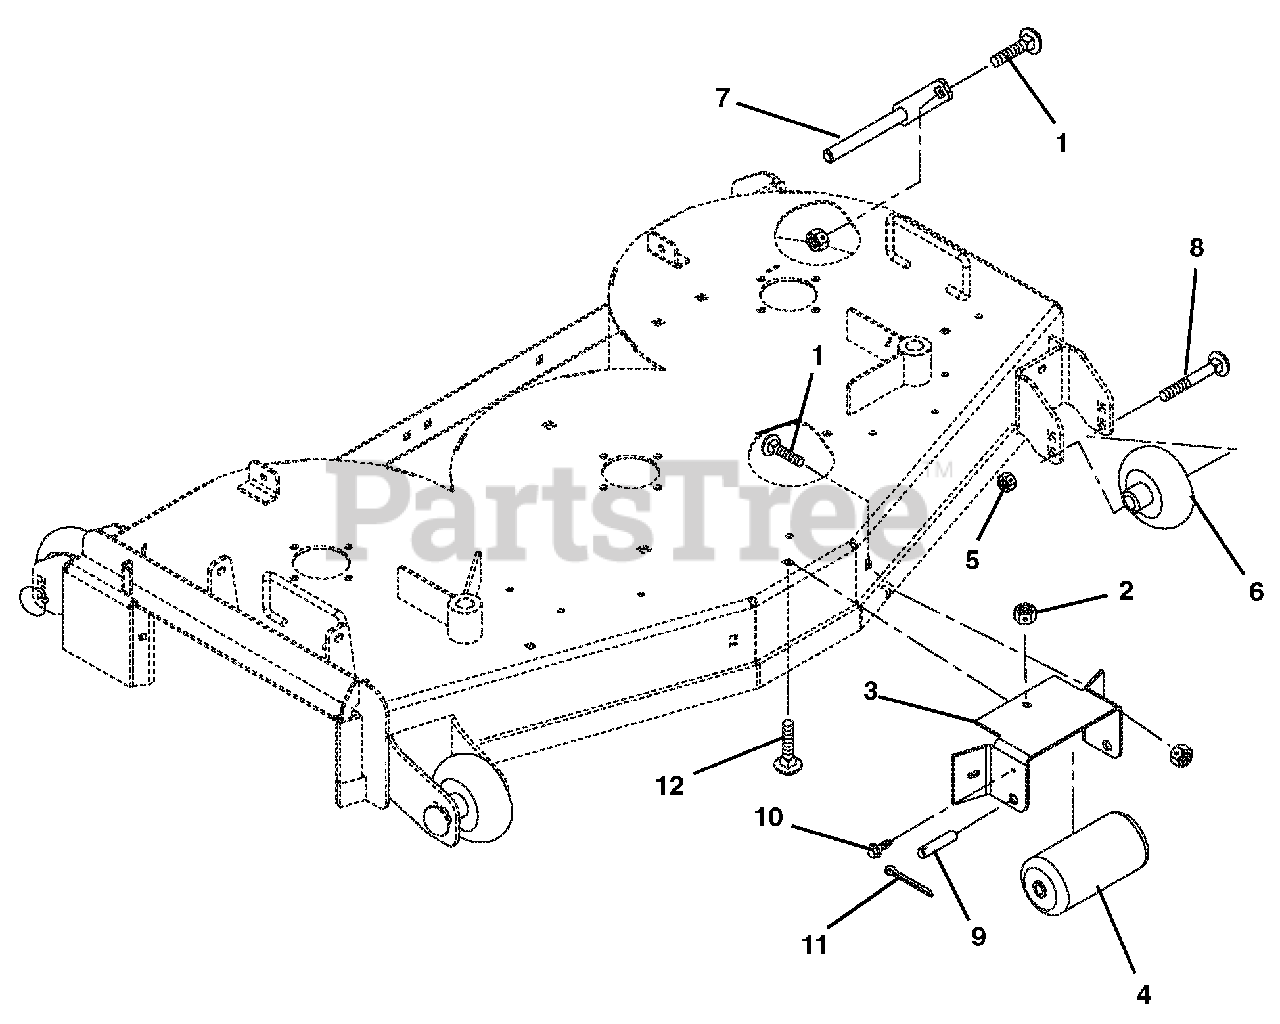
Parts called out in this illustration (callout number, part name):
1	@BLT-RDHDSQNK .38-16X1.00 G5YZ
2	@NUT-LK-TOP-FLG .38-16 YWZC
3	BRACKET - ANTI-SCALP ROLLER
5	@NUT-LK-TOP-FLG .50-13 YWZC
6	WHEEL, 3X5
7	WMT- WHEEL RETAINER
8	BLT-RDHDSQNK .50-13X4.50 G2 YZ
10	SCR-TAP .25-20X.50 HWH TR YWZ
11	@PIN-CTR .25X2.00 YWZC
12	@BLT-RDHDSQNK .38-16X.75 G5YZ
